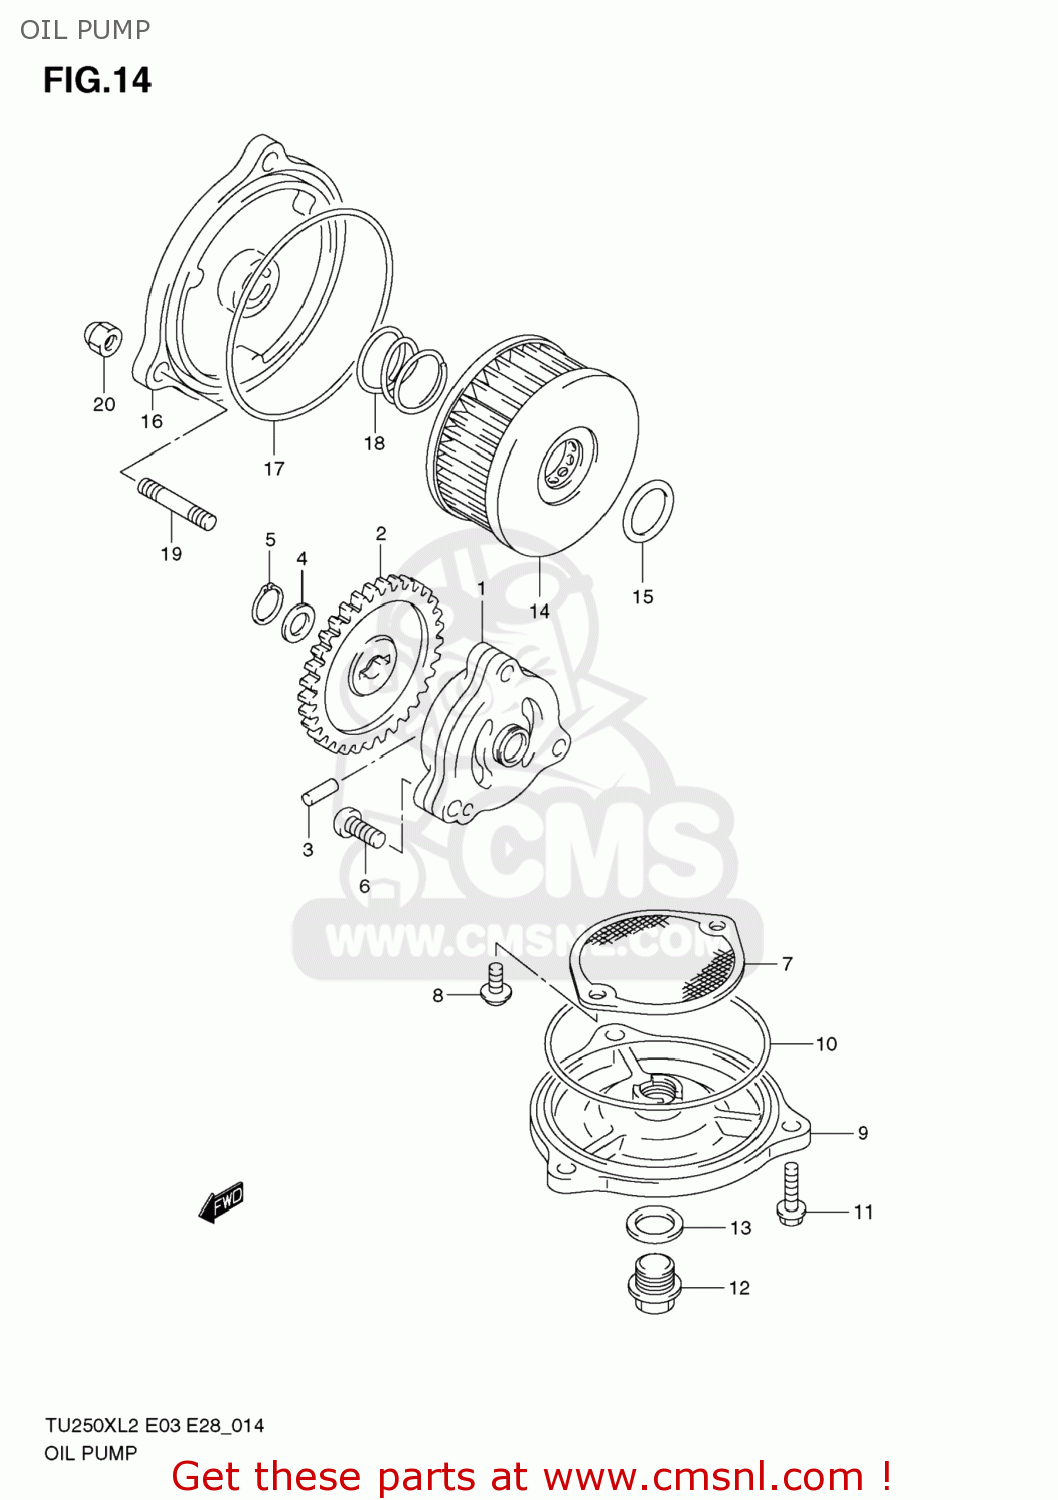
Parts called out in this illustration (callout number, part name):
1	PUMP ASSY,ENGINE OIL
2	GEAR,OIL PUMP DRIVEN
3	PIN(4X18.5)
4	SHIM(10X18X0.5)
5	CIRCLIP
6	BOLT
7	STRAINER,ENGINE OIL
8	SCREW
9	CAP,OIL STRAINER
10	O RING(D:2.4,ID:85)
11	BOLT
12	PLUG(14X12)
13	GASKET(13.8X18.8X4.8) (NAS)
14	FILTER ASSY,ENGINE OIL
15	O RING(D:2.4,ID:15.8)
16	CAP,OIL FILTER
17	O RING(D:2.4,ID:73)
18	SPRING
19	BOLT,STUD
20	NUT
